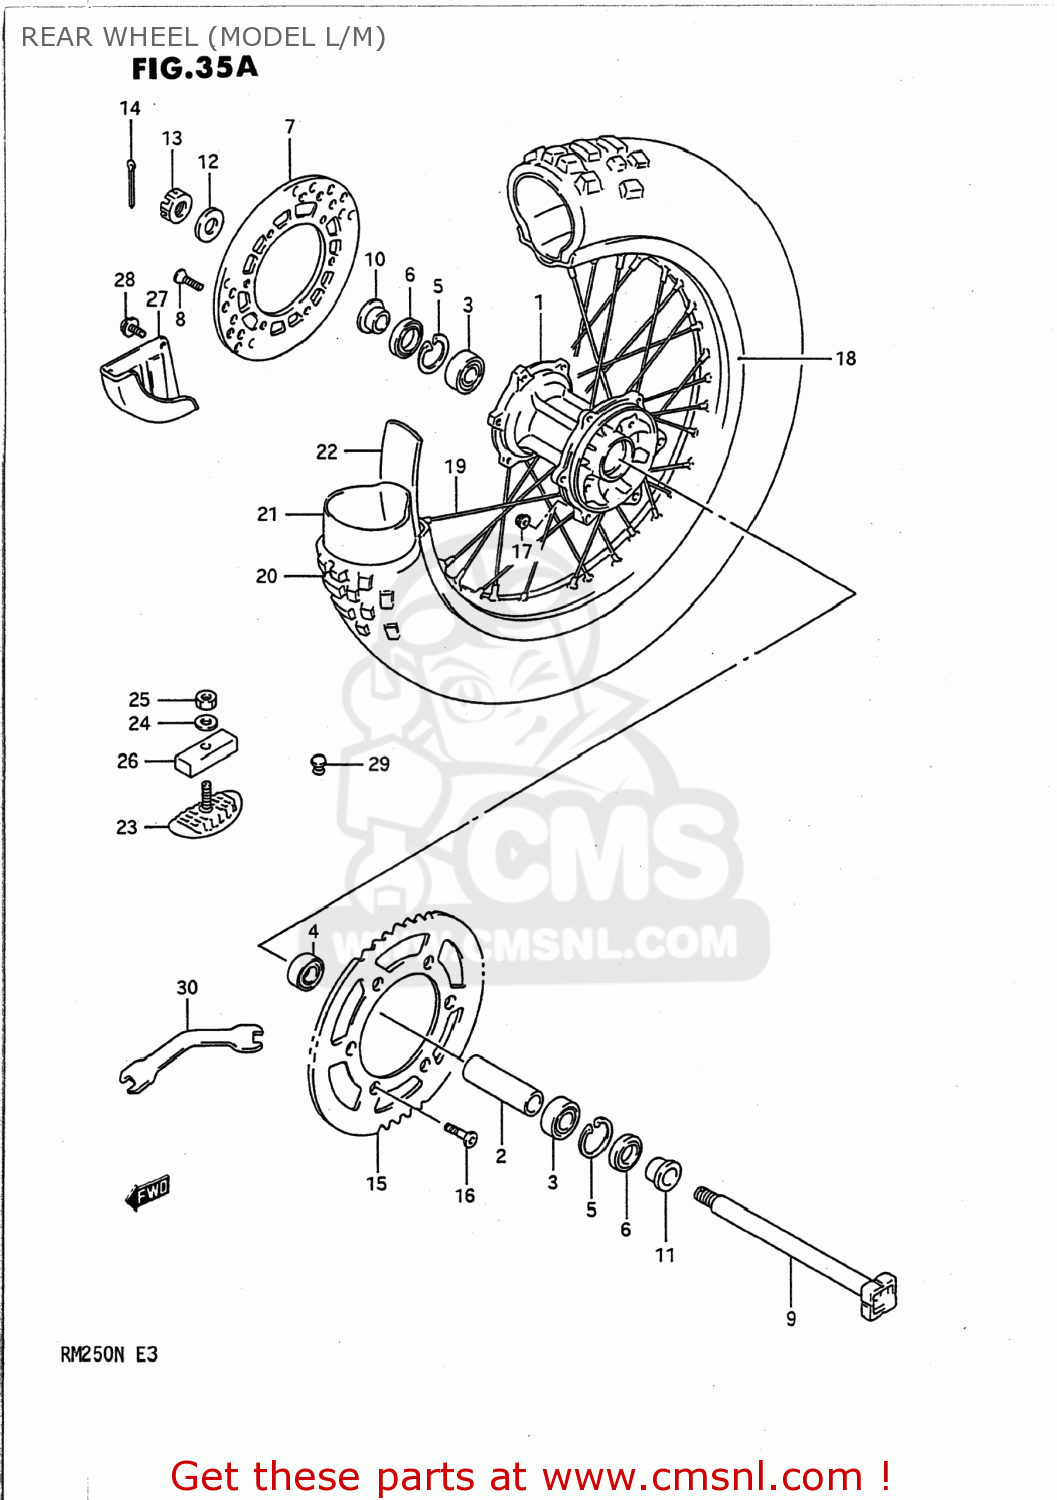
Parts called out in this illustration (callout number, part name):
1	HUB,RR
2	SPACER,RR HUB BEARING
3	BEARING WHEEL REAR(20X47X14)
4	BALL BEARING
5	CIRCLIP,14MM
6	SEAL,OIL(26X47X5)
7	DISC,REAR BRAKE
8	SCREW
9	AXLE,RR
10	SPACER,RR AXLE,R
11	SPACER,RR AXLE,L
12	WASHER (19X32X3.2)
13	NUT 18MM
14	PIN,COTTER
15	SPROCKET,REAR
16	BOLT(8X30.5)
17	NUT
18	RIM,RR WHEEL(2.15X19 AL)
19	SPOKE SET,RR WHEEL
20	TIRE
21	TUBE ASSY,WHEEL INNER
22	PROTECTOR,WHL INR TUBE
23	STOPPER,BEAD
24	WASHER
25	NUT
26	CUSHION,BEAD STOPPER
27	COVER,REAR DISC
28	BOLT
29	CAP(OD:12)
30	SPANNER,OPEN
